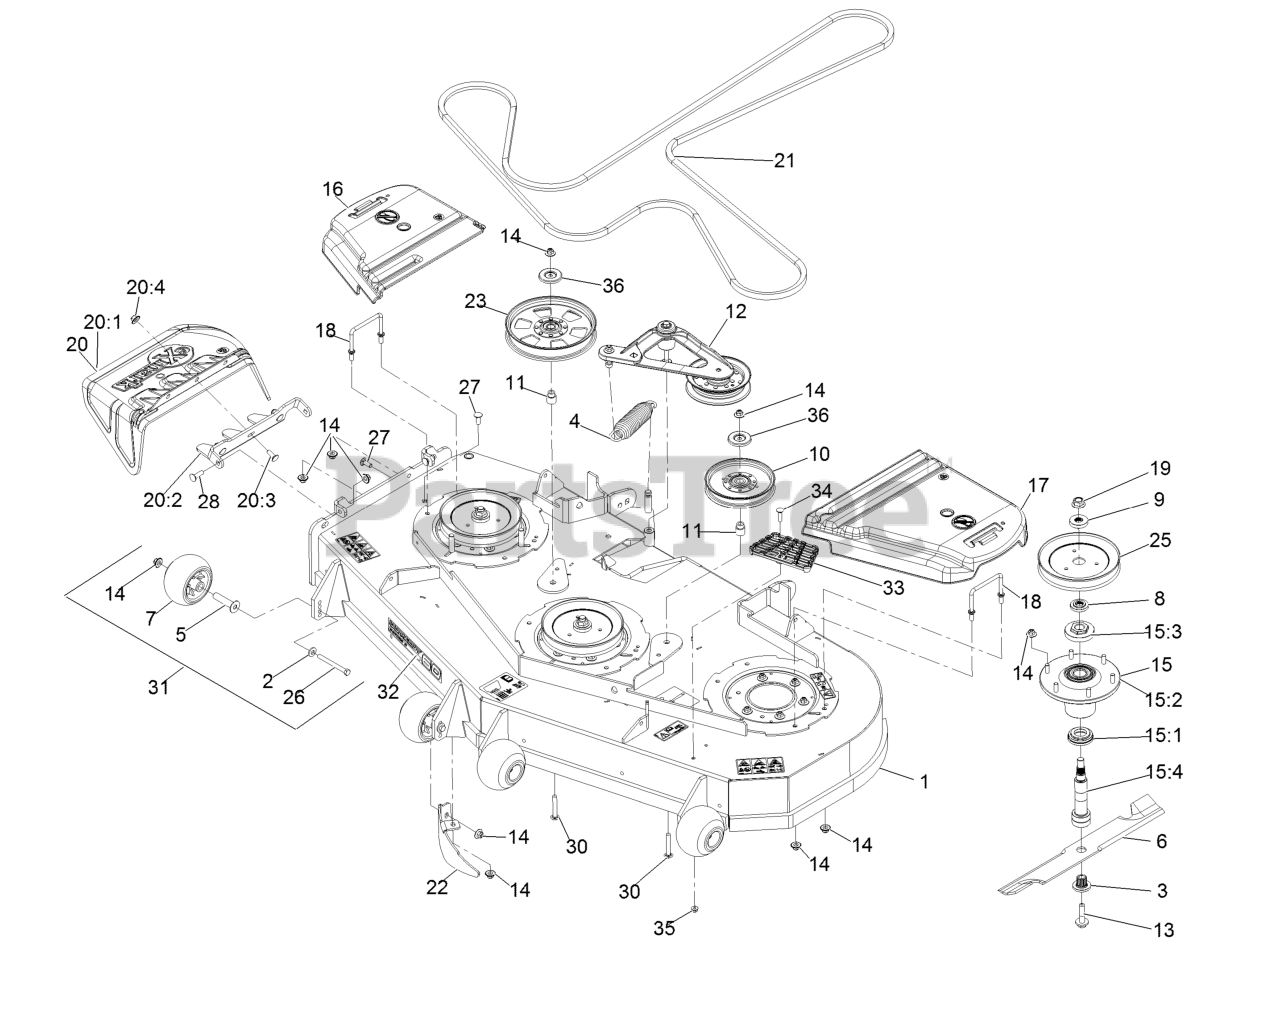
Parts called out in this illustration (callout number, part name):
1	DECK ASM,W/DECALS 60
2	WASHER-BELLEVILLE
3	BUSHING,SPLINED
4	SPRING-EXTENSION
5	AXLE, ROLLER
6	Blade-Extreme 2, 20.50"
7	ROLLER-SCALP, ANTI
8	SPACER,SPLINED STEPPED
9	SPACER,SPLINED
10	IDLER-PULLEY
11	BUSHING-IDLER
12	DECK IDLER ASM
13	SCREW,SEMS 1/2-20 X 2.19
14	Nut-Nyloc 3/8-16 Flg
15	ASM,SPINDLE HOUSING
15:1	GUARD,BOTTOM
15:2	ASM,CUTTER HOUSING
15:3	NUT, SPINDLE 7/8-14
15:4	SPINDLE,DOUBLE SPLINE
16	COVER-BELT, RH
17	COVER-BELT, LH
18	WIREFORM-COVER
19	NUT-FLANGE, CENTERLOCK
20	ASM,DISCHARGE CHUTE
20:1	CHUTE,DISCHARGE
20:2	BRACKET,DISCHARGE CHUTE
20:3	SCREW-CARR
20:4	Nut-Nyloc 3/8-16 Flg
21	BELT,V-5V-198.75
22	DOGLEG - LZ60
23	PULLEY-IDLER, FLAT
25	SHEAVE,BLADE DRIVE 7.25
26	SCREW-HH 3/8-16 X 3 3/4 GR 8
27	SCREW-CARR
28	Bolt-Carriage 3/8-16 X 1 1/4
30	SCREW-CARR
31	KIT, ANTI-SCALP ROLLER
32	DECAL, 606
33	STEP-DECK
34	Bolt-Carriage 5/16-18 X 1 1/4
35	NUT-HF, NI
36	SHIELD-DUST
